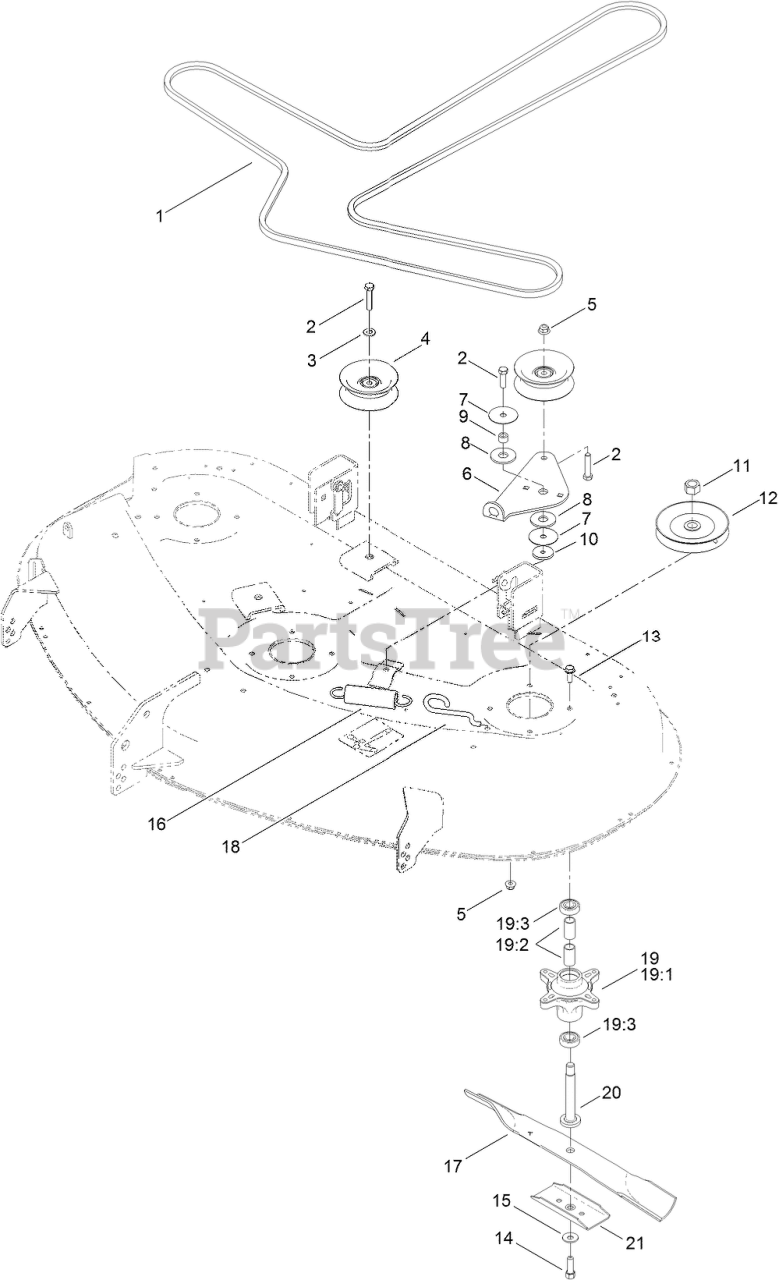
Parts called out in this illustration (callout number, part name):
1	V-BELT
2	SCREW-HH
3	WASHER-FLAT
4	PULLEY-IDLER, FLAT
5	NUT-HF, NI
6	ARM-IDLER
7	WASHER
8	WASHER-FRICTION, COMPOSITE
9	SPACER
10	SCREW-HH
11	NUT-HEX
12	Pulley
13	SCREW-TAPTITE
14	SCREW-HH
15	WASHER-BELLEVILLE
16	SPRING-EXTENSION
17	BLADE-21.6 INCH
18	HOOK-RETURN, SPRING
19	SPINDLE ASM
19:1	SPINDLE
19:2	SPACER
19:3	BEARING-BALL
20	SHAFT-SPINDLE
21	STIFFENER-BLADE
